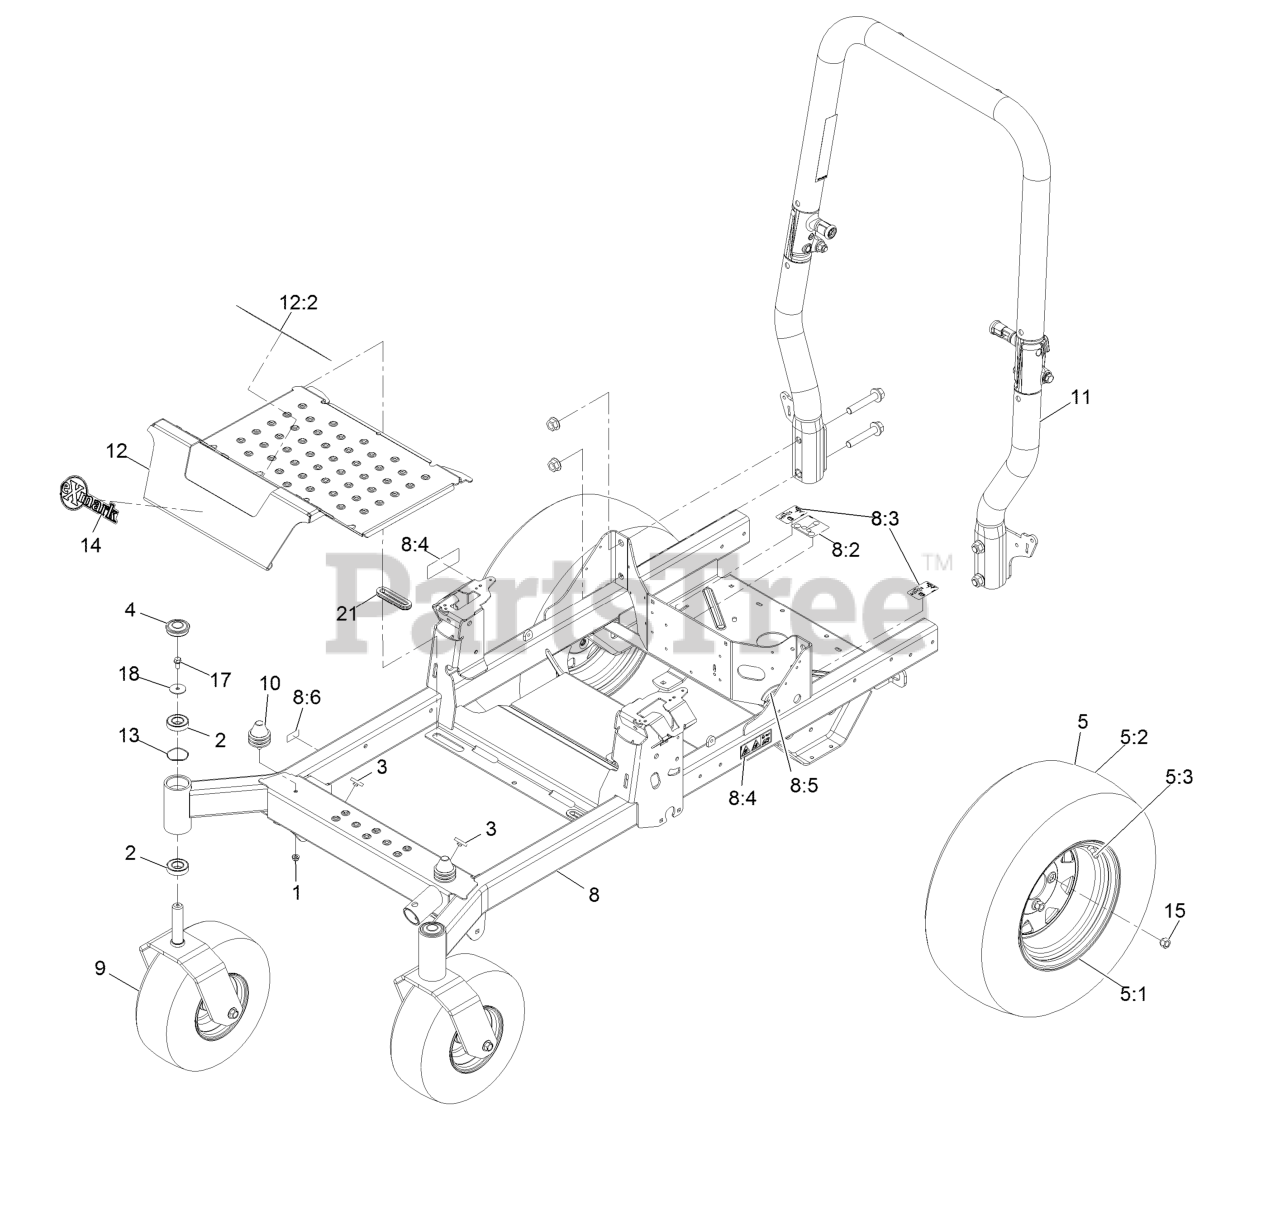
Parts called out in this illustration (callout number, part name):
1	Nut-Nyloc 5/16-18 Flg
2	Bearing-Ball
3	Bumper-Push-In, Rubber
4	Cap-Grease
5	Wheel And Tire ASM
5:2	Tire
5:3	Stem-Valve
8	Frame ASM
8:2	Decal-Routing, Belt
8:3	Decal-Release, Drive
8:4	Decal-Warning
8:5	Strip-Seal
8:6	Decal-Patent
10	Isolator
11	ASM-ROPS Tapered
12	PAN-Floor
12:2	Decal-Danger
14	Decal-Exmark Logo
15	Nut-Lug 1/2-20
17	Screw-HH Flg 5/16-18 X 3/4
18	Washer-Flat
21	Grommet-Rubber
